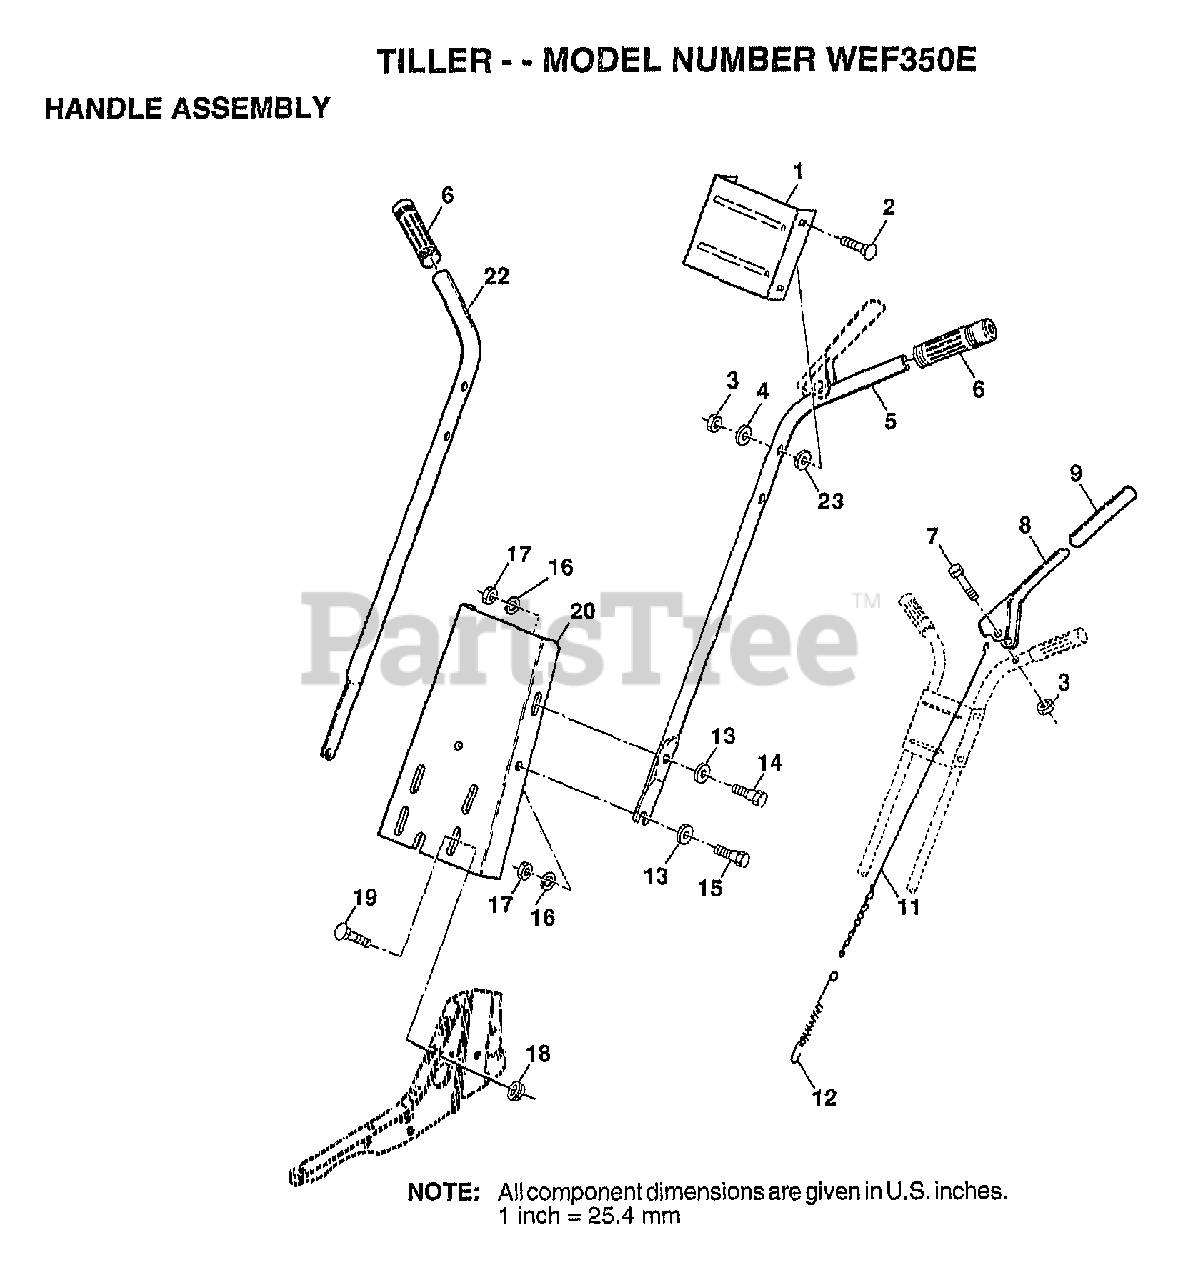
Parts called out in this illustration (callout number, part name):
1	PANEL.CNTRL.HDLE.
2	BOLT
4	WASHER
5	HANDLE LH
7	BOLT.HEX.5/16-1.5
8	LEVER.CONTROL.TINE
9	GRIP T
12	SPRING EXT TI
13	WASHER
15	BOLT
16	LOCKWASHER
17	NUT.HEX.5/16-18
18	NUT
19	BOLT
20	PANEL.HANDLE.TILL
22	HANDLE RH
23	WASHER
